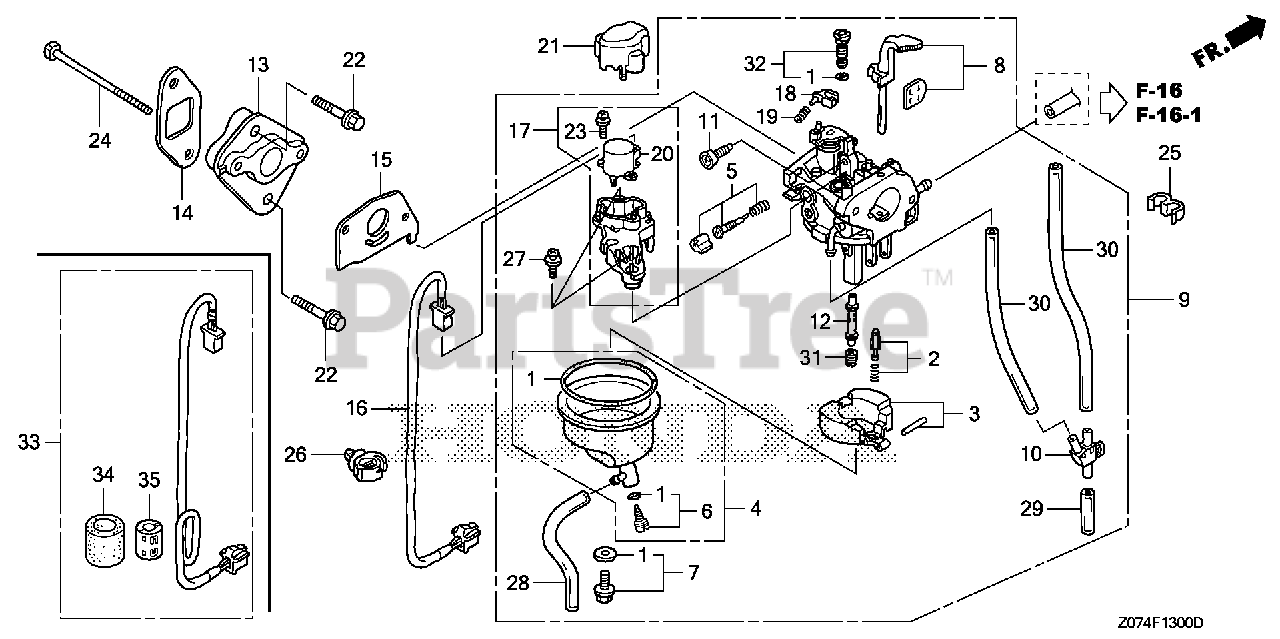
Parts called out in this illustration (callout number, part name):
1	GASKET SET (CARBURETOR NO.)
2	VALVE SET, FLOAT (CARBURETOR NO.) (SEAT NOT INCLUDED)
4	CHAMBER SET, FLOAT (CARBURETOR NO.)
5	SCREW SET (Honda Code 4219879). (CARBURETOR NO.)
6	SCREW SET, DRAIN (CARBURETOR NO.)
7	SCREW SET (CARBURETOR NO.)
9	CARBURETOR ASSY. (BF30E D/E)
10	JOINT, AIR VENT TUBE (CARBURETOR NO.)
11	SCREW, THROTTLE STOP
12	NOZZLE, MAIN
13	INSULATOR, CARBURETOR
14	GASKET, INSULATOR
15	GASKET, CARBURETOR
16	SUB-WIRE ASSY.
17	MOTOR ASSY., THROTTLE CONTROL
18	LEVER, LINK (CARBURETOR NO.)
19	SPRING, COMPRESSION COIL (CARBURETOR NO.)
20	MOTOR, THROTTLE CONTROL (CARBURETOR NO.)
21	COVER, THROTTLE MOTOR
22	BOLT, FLANGE (6X25) (NSHF)
23	SCREW-WASHER (3X8)
24	BOLT, HEX. (5X95)
25	CLAMP, TUBE (7X8)
26	CLIP, WIRE HARNESS (25MM)
27	SCREW-WASHER (4X10)
28	BULK HOSE, VINYL (3.5X6.5X8000) (9500(95003-05001-60M) (CARBURETOR NO.)
29	BULK HOSE, VINYL (4X7X8000) (95003-07(95003-07001-60M) (CARBURETOR NO.)
30	BULK HOSE, VINYL (4X7X8000) (95003-07(95003-07001-60M) (CARBURETOR NO.)
31	JET, MAIN (#58) Use from Engine SN BF22B D.
31	JET, MAIN (#60)
31	JET, MAIN (#62) (CARBURETOR NO.)
32	JET SET, PILOT (#35)
